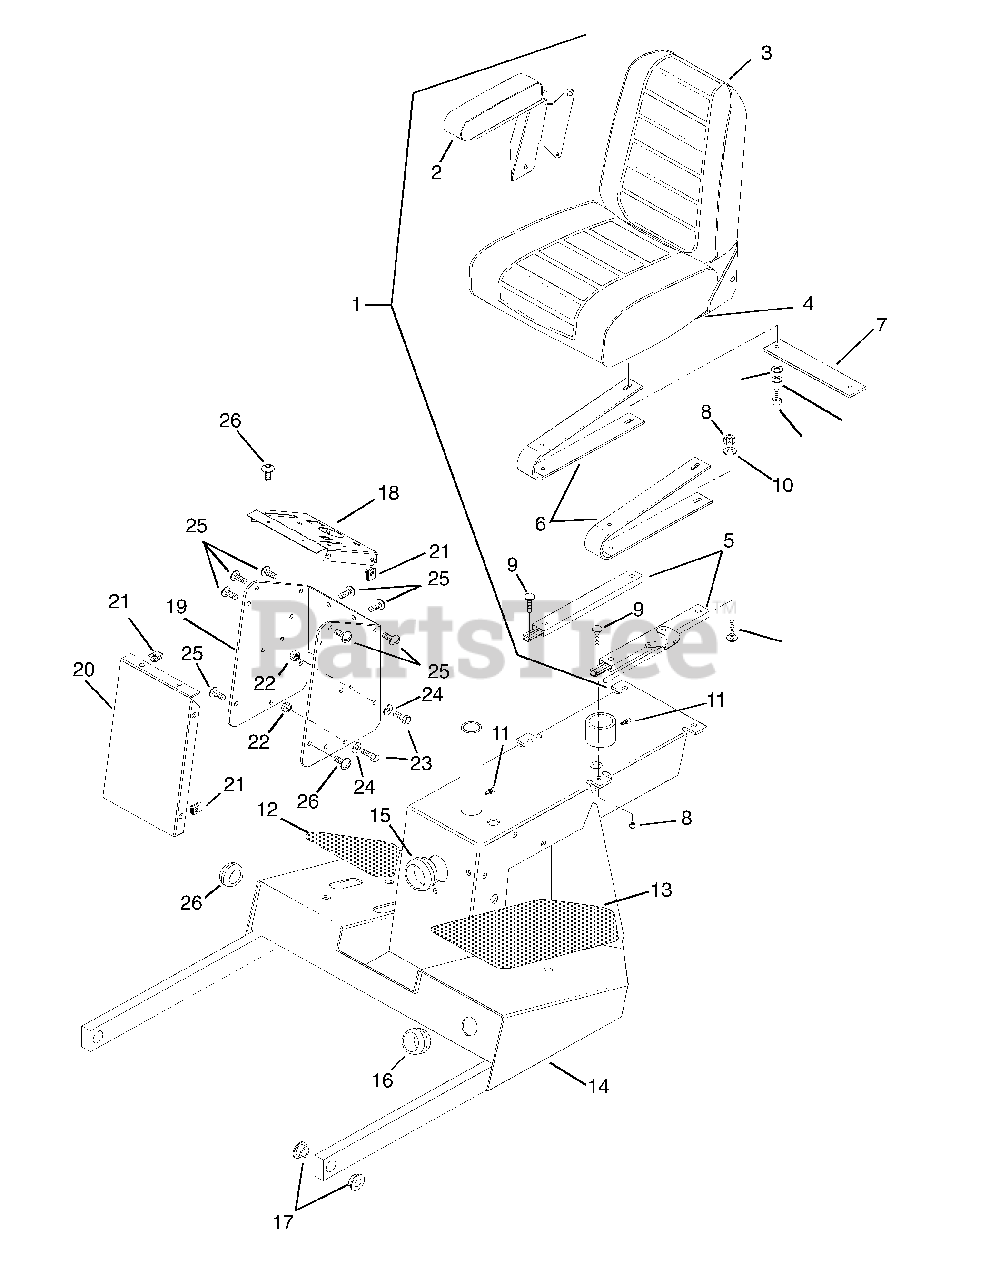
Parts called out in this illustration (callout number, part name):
1	Assembly-Seat (Contains Items 2-5)
2	Arm Rest-Right Hand
2	Arm Rest-Left Hand
3	Cusion-Back
4	Seat Cusion w/Switch
5	Seat Slides with Handle
6	Spring-Seat
7	Bracket-Seat
8	Nut-Locking-Center .31-18
9	Bolt-Round Head Square Neck .31-18 x 1.00 Grade 5
10	Washer-Flat-Steel .344 x .688 x .065
11	Fitting-Lube .25-28 x .256
12	Cover-Footboard Right Hand
13	Cover-Footboard Left Hand
14	Weldment-Rear Frame
15	Grommet
16	Grommet 1.50 x 1.75 x 2.12
17	Bushing-Flange .762 x 1.0 x .580 x 1.48
18	Panel-Instrument
19	Panel-Support Instrument Panel
20	Front Panel
21	Nut-Retainer .25-20 x .56
22	Nut-Locking-Center .25-20
23	Bolt-Hex .25-20 x 1.00 Grade 5
24	Washer-Flat-Steel .281 x .620 x .065
25	Screw-Machine .25-20
26	Grommet 1.25 x 1.5 x 1.81
